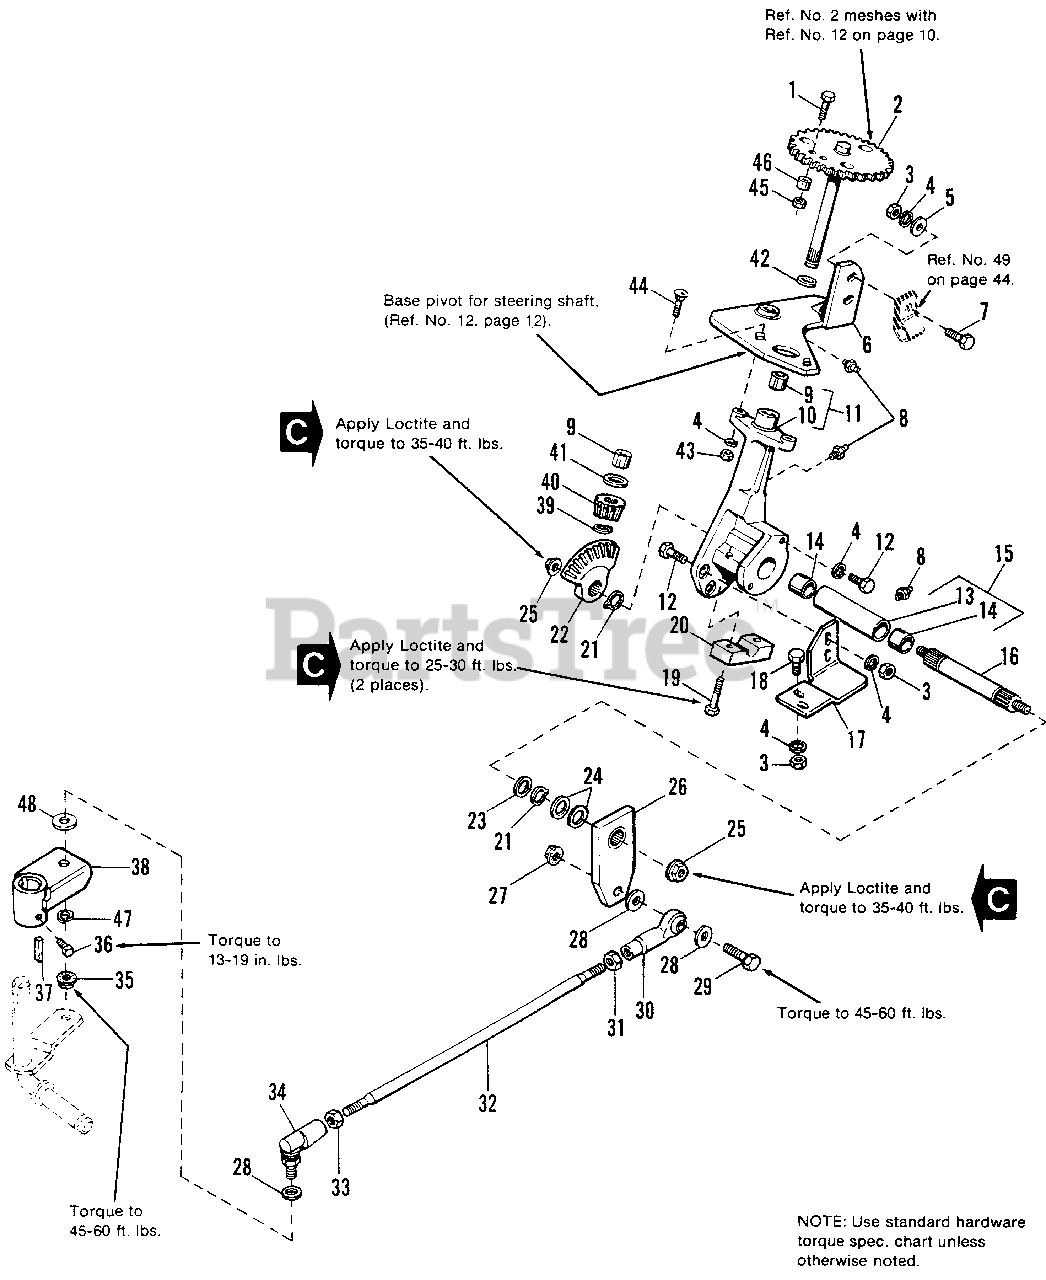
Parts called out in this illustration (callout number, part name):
1	CAPSCREW, Hex Hd., 5/16-18 x 1-1/4
2	SHAFT & GEAR ASSY. (76 Teeth)
3	NUT, Hex, 3/8-16
4	LOCKWASHER 3/8
5	WASHER, Plain, 3/8 X 7/8 x 5/64
6	PLATE ASSY, Gear w/Bushings (Incl. Qty. 2 of Ref. No.9)
7	CAPSCREW, Hex Hd., 3/8-16 x 1-1/2
8	FITTING, Lub.
11	HOUSING, Steering (Incl. of Ref. Nos. 9 (Qty. 2) & 10)
12	CAPSCREW, Hex Hd., 3/8-16 x 1
15	TUBE ASSY., Bearing (Incl. Ref. Nos. 13 & 14, Qty. 2)
16	SHAFT, Steering Arm
17	BRACKET, Support
18	CAPSCREW, Hex Hd., 3/8-16 x 7/8
19	CAPSCREW, Hex Hd., 3/8-16 x 1-3/4
20	CLAMP, Bearing Tube
21	RING, Retainer
22	GEAR, Bevel (14 Teeth)
23	WASHER, 1 x 1-3/8 x 1/64
24	WASHER, 1 x 1-5/8 x 1/64
25	LOCKNUT, Hex, Flange, 1/2-13
26	ARM ASSY., Steering, Splined
27	NUT, Hex, Centerlock, 1/2-13
28	WASHER, Plain, 17/32 x 3/4 x 5/64
29	CAPSCREW, Hex Hd., 1/2-13 x 1-1/2
31	NUT, Hex, Jam, 1/2-20
32	DRAG LINK
33	NUT, Hex, Jam, 1/2-20
35	NUT, Hex, Centerlock 1/2-20
36	SETSCREW, Sq. Hd., 5/16-18 x 1/2
37	KEY, Parallel, 1/4 x 1/4 x 1-1/2
38	ARM ASSY., Spindle
39	RING, Retaining, 3/4
40	PINION, Bevel, (14 Teeth)
41	WASHER, Thrust, 49/64 x 1-3/8 x 1/1/6
42	WASHER, Curved
43	LOCKNUT, Hex, 3/8-16
44	BOLT, Carriage, 3/8-16 x 1-1/4
45	NUT, Hex Centerlock, 5/16-18
46	SPACER, Brake
47	LOCKWASHER, 1/2
48	WASHER, Hardened, 1/2 x 1-1/4 x 3/16
